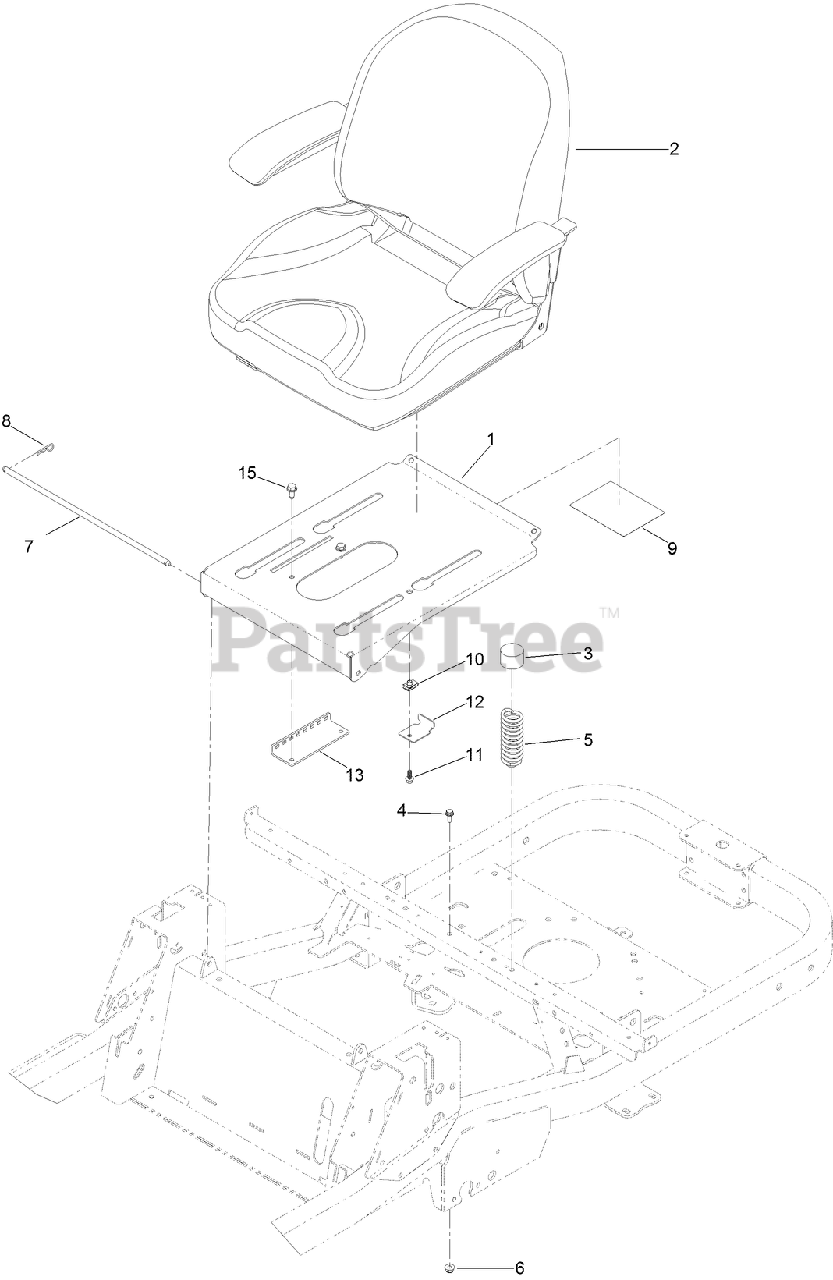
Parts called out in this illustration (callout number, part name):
1	PAN-SEAT
2	SEAT ASM
3	CAP-PROTECTOR
4	SCREW-HHF
5	SPRING-COMPRESSION
6	NUT-HF, NI
7	ROD-STOP
8	PIN-COTTER
9	DECAL-MAINTENANCE
11	SCREW-HHF
12	BRACKET-STOP, SEAT
13	BRACKET-LATCH, SEAT
15	SCREW-HWHTF
